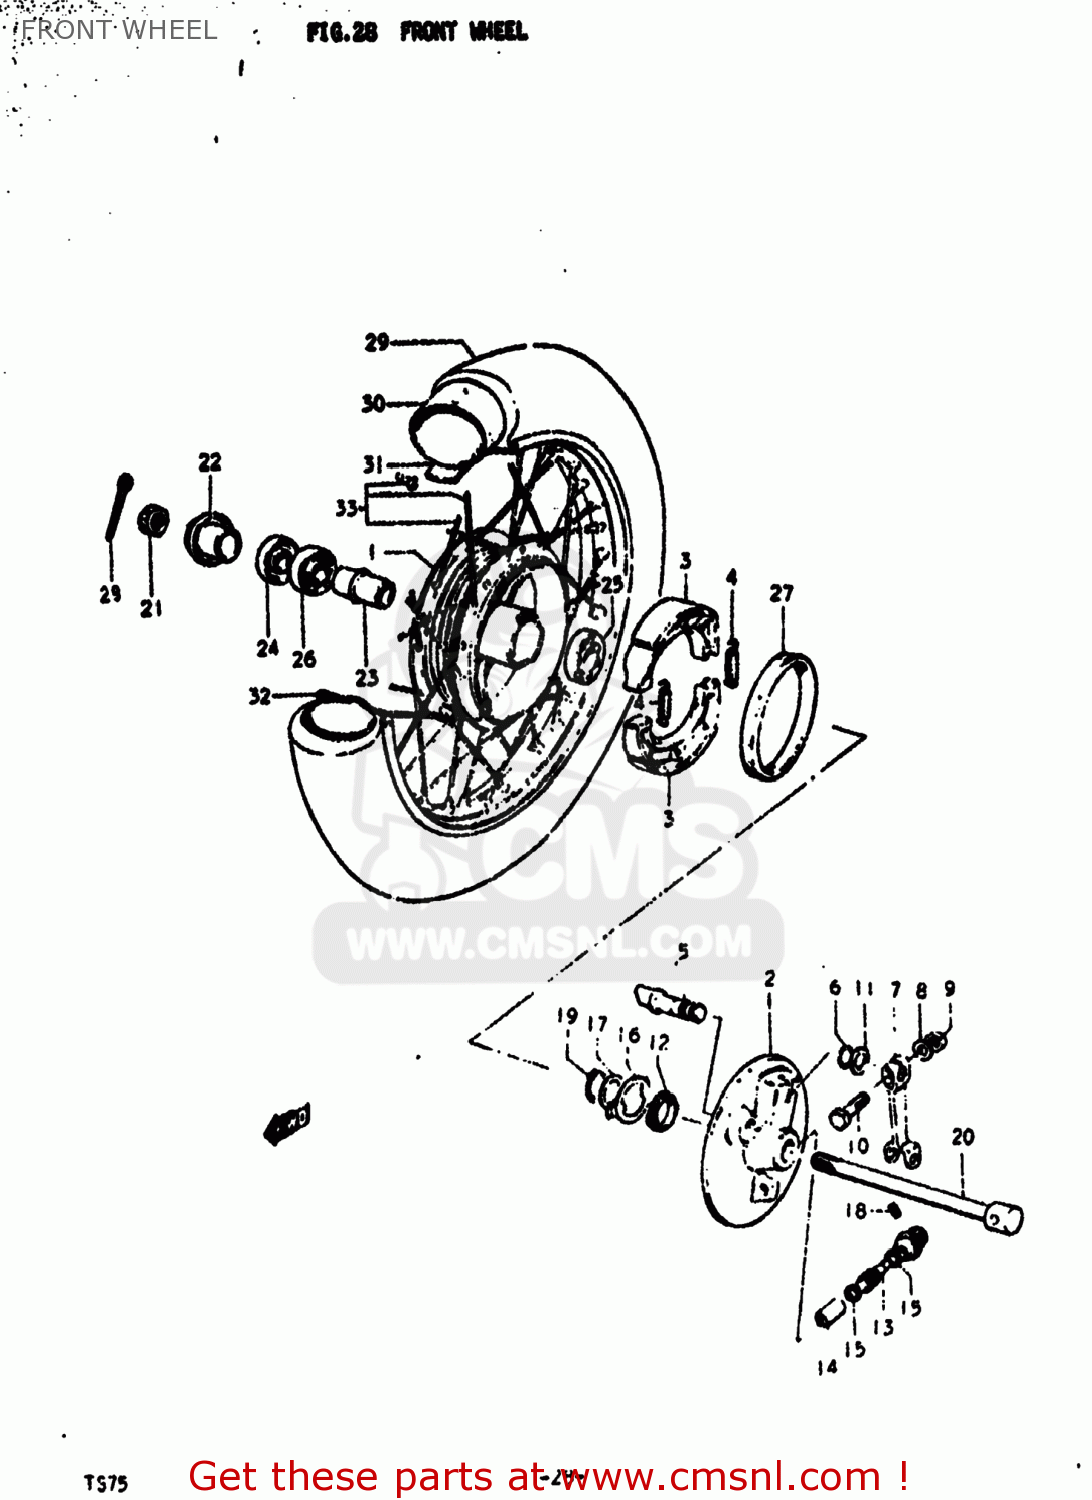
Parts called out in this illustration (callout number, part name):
1	HUB,FRONT
2	CAM,FR BRAKE
3	SHOE,BRAKE
4	SPRING(L:34)
6	O RING(D:2.5,ID:11.4)
7	LEVER,FR BRAKE CAM
8	WASHER
9	NUT
10	BOLT
11	WASHER(12.5X20X1)
12	GEAR,SPEEDOMETER
13	PINION,SPEEDOMETER
14	BUSH,METER GEAR OUTER
15	WASHER (5.1X9X0.4)
16	DRIVER,SPEEDOMETER GEAR
17	WASHER(16X22X1)
18	SCREW
19	CIRCLIP
20	AXLE,FRONT
21	NUT
22	SPACER,FRONT AXLE,RIGHT
23	SPACER,FRONT HUB BEARING
24	SEAL,OIL(15X31X5)
25	BEARING, LH
26	BEARING
27	OIL SEAL (43X58X7)
28	COTTER PIN
29	TIRE,FRONT
30	TUBE,INNER
31	PROTECTOR,WHEEL,INNER
32	RIM,FRONT WHEEL
33	SPOKE SET,FRONT
